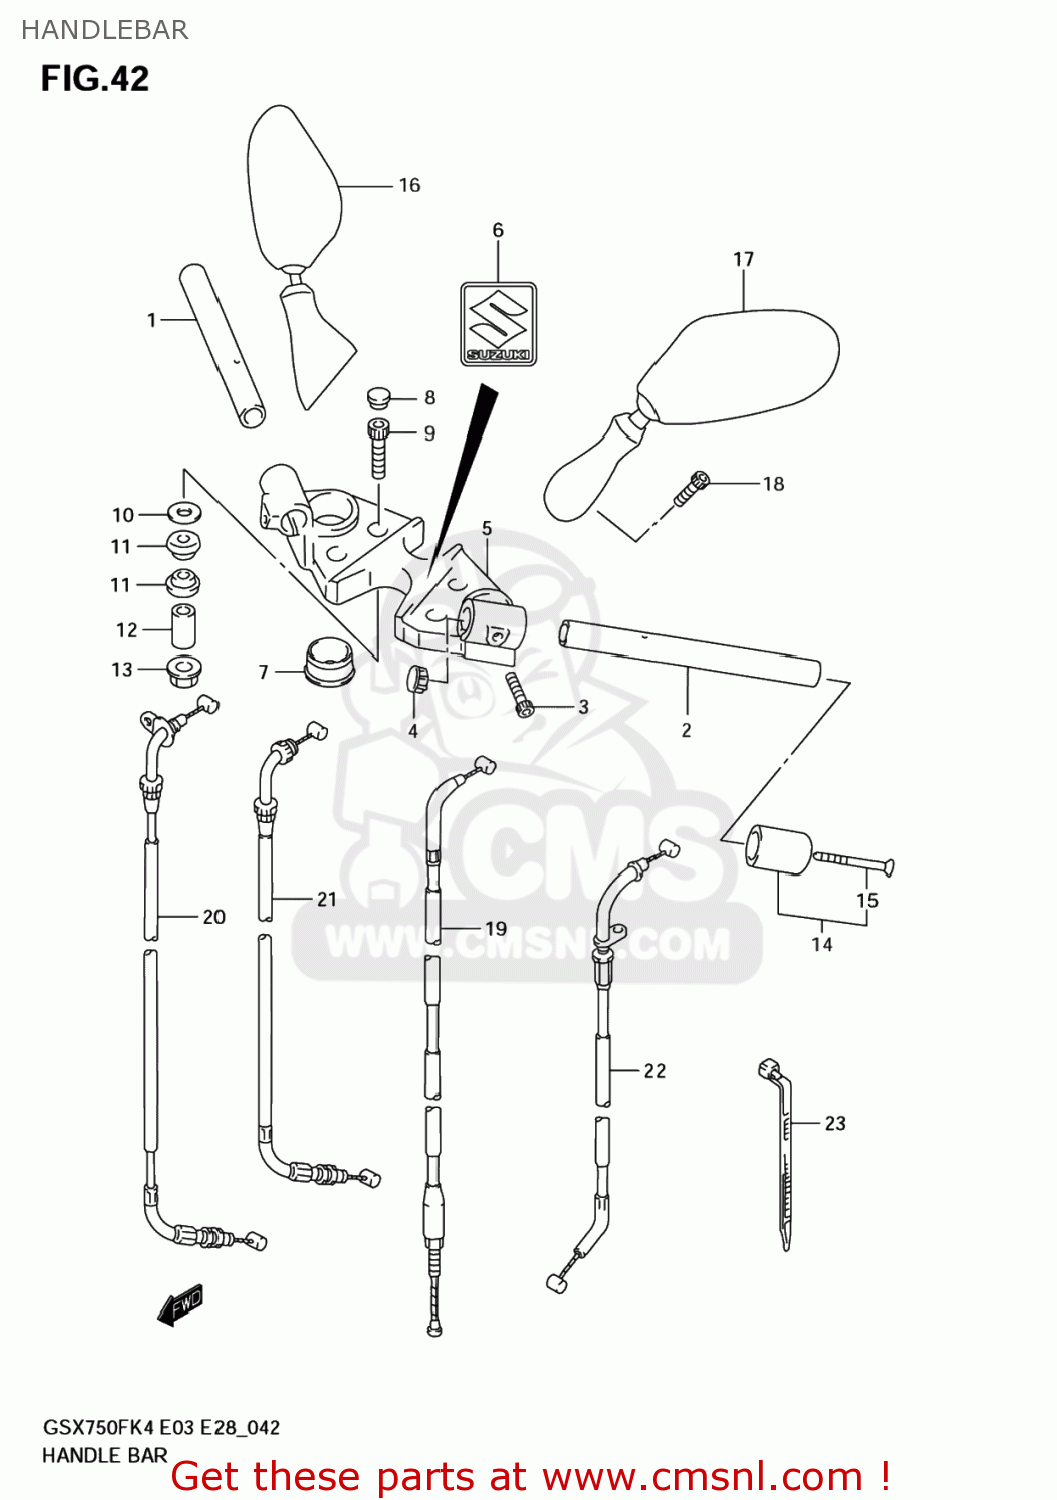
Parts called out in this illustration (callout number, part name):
1	HANDLEBAR,R
2	HANDLEBAR,L
3	BOLT
4	CAP,HANDLEBAR
5	HOLDER,HANDLEBAR
6	EMBLEM,S
7	CUSHION,HANDLE HOLDER
8	CAP(OD:12)
9	BOLT(10X70)
10	WASHER(10.5X30X3.2)
11	CUSHION,UPR BRACKET
12	SPACER,HANDLEBAR BRACKET
13	NUT
14	BALANCER SET,HANDLEBAR
15	SCREW
16	MIRROR ASSY,RR VIEW,R
17	MIRROR ASSY,RR VIEW,L
18	BOLT,OIL FILLE
19	CABLE ASSY,CLUTCH
20	CABLE ASSY,THROTTLE NO.1
21	CABLE ASSY,THROTTLE NO.2
22	CABLE,STARTER
23	CLAMP(L:235)
